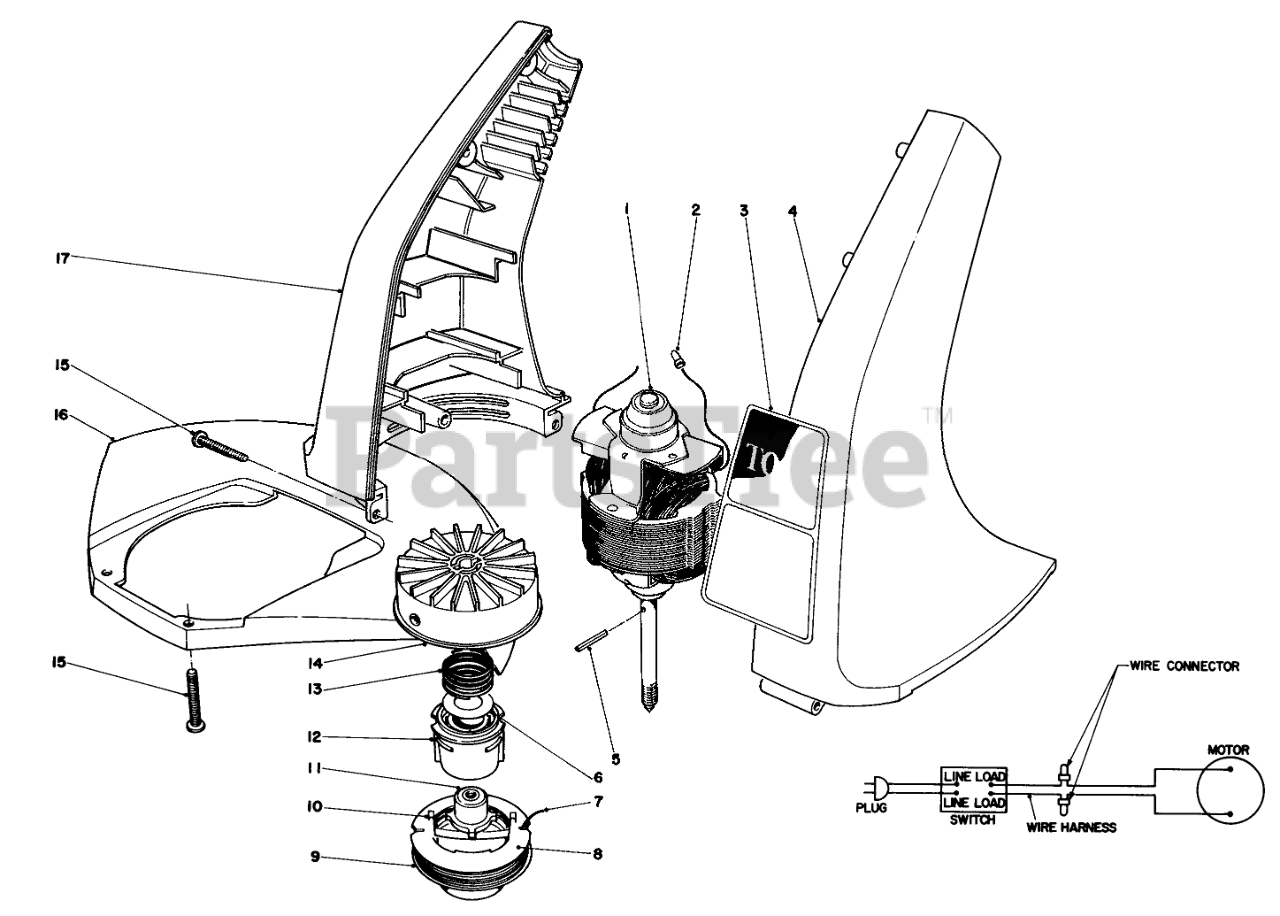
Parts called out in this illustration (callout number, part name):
1	Motor
2	CONNECTOR WIRE JOINT
3	DECAL - 1100 CANADIAN
4	Housing-Left Hand
5	COIL PIN
6	WASHER-FLAT
7	LINE-FILIMENT
8	Empty SPooI
9	Cutting Line (50 .065" Dia.)
10	SADDLE-SPOOL CAP
11	Driver
12	SPOOL CORE
13	SPRING COMPRESSION
14	DRUM W/EYELET
15	Screw
16	Shield
17	R.H. HOUSING, 1100
